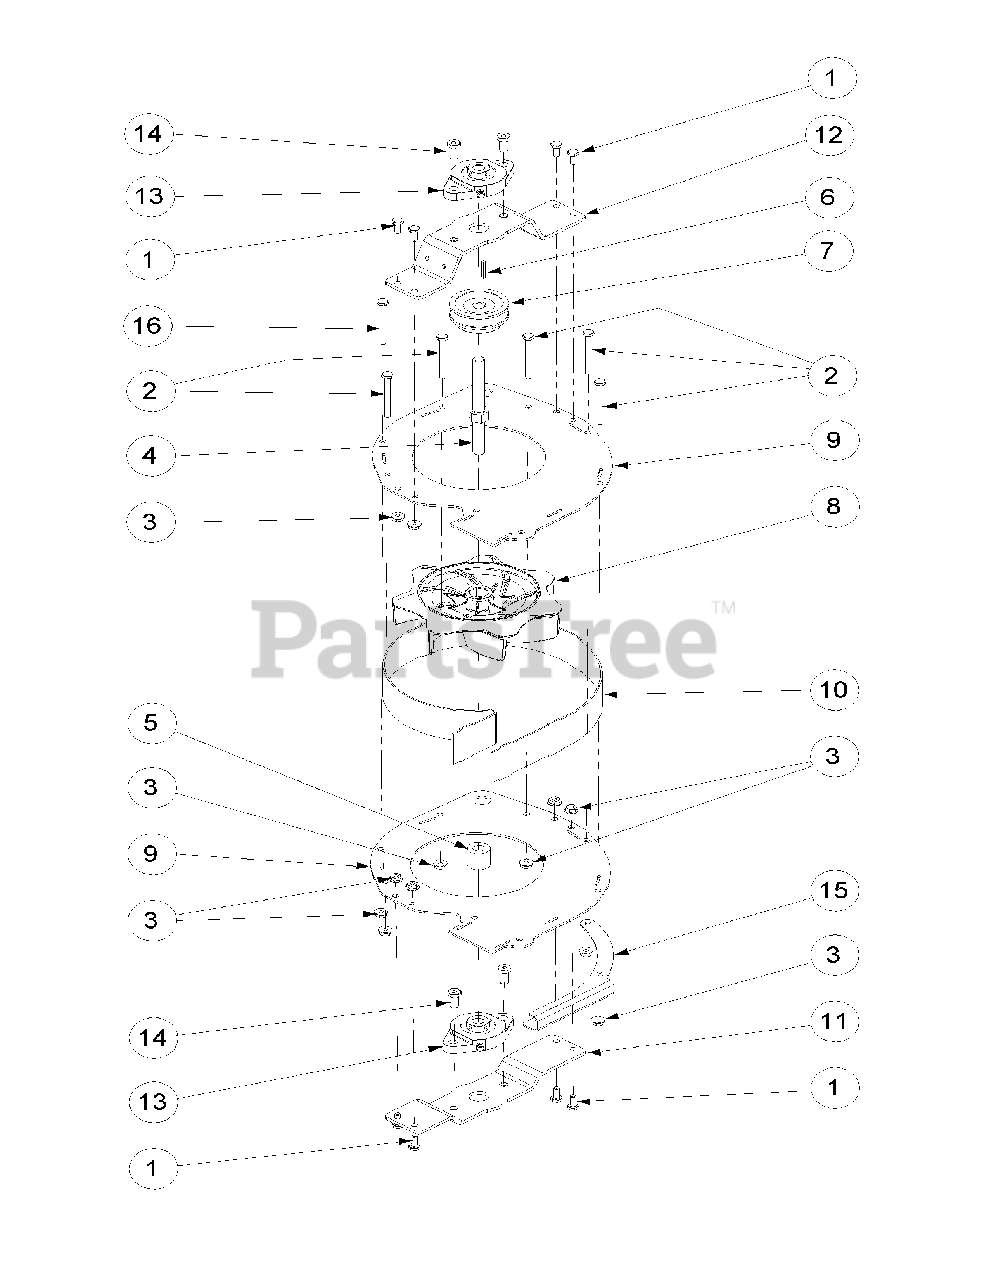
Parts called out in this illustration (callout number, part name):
1	HHCS, 1/4-20 x 0.620
2	HHCS, 1/4-20 x 2.50
3	Hex Nut Flange Lock, 1/4-20
4	Blower Shaft
5	Blower Spacer
6	Key, 1/8 x 1/8 x 1.00
7	Cast Pulley, .500 ID x 2.50 OD
8	Blower Impeller
9	Blower Housing Cover
10	Blower Housing Band
11	Bottom Bearing Mounting Plate
12	Top Bearing Mounting Plate
13	Flange Bearing
14	Socket Head Screw, 3/8-16 x .75
15	Guard Deflector
16	HHCS, 1/4-20 x 2.75
